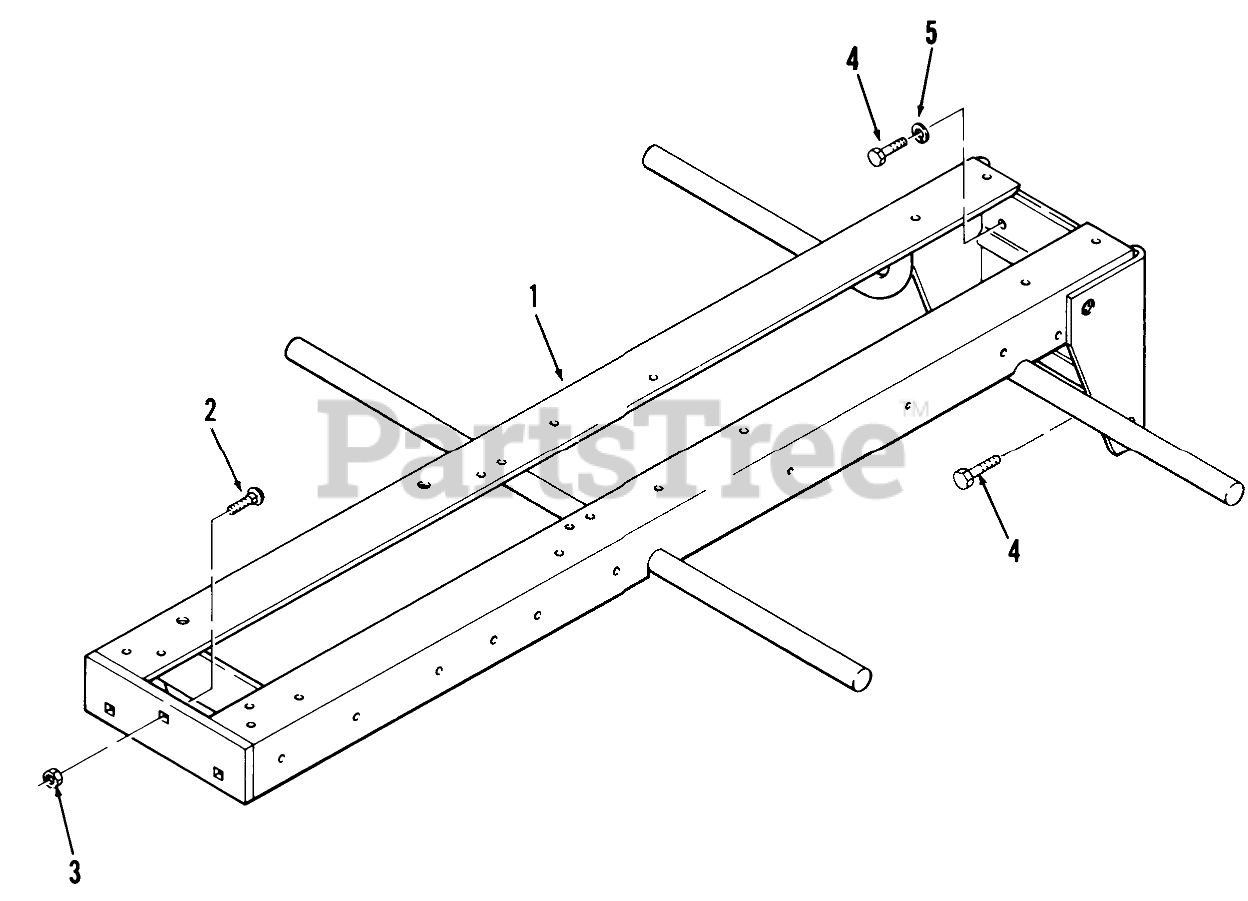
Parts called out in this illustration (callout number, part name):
1	Frame
2	Bolt
3	Nut
4	Bolt
5	LOCKWASHER
